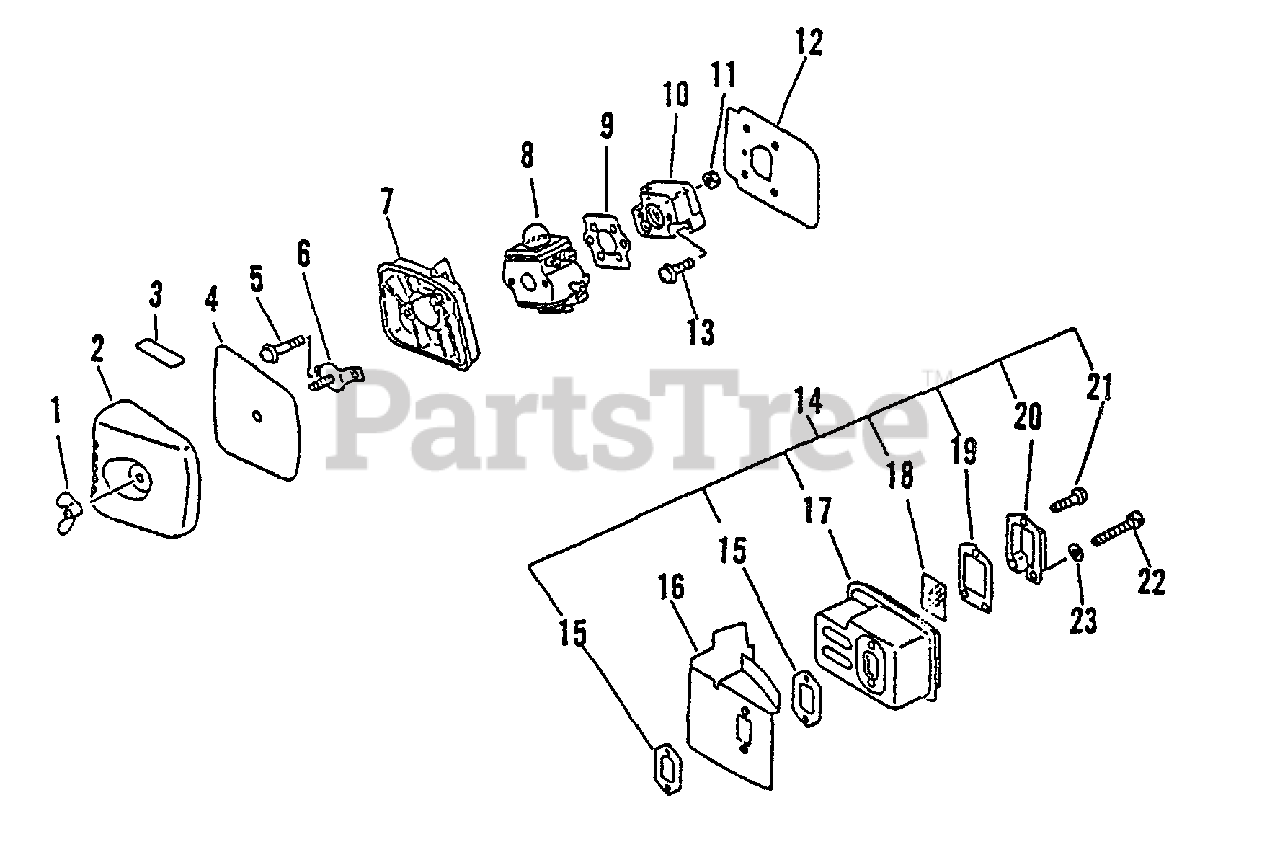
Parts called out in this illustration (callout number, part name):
1	WINGNUT - 6
2	COVER, AIR FILTER
3	LABEL - CHOKE
4	FILTER, AIR
5	SCREW - 5X64
6	PLATE, PREVENT
7	AIR FILTER CASE ASSY
8	CARBURETOR C1U-K17
9	GASKET, INTAKE
10	INSULATOR, INTAKE
12	SHIELD, INTAKE
13	SCREW - 5X20
14	MUFFLER ASSY
15	GASKET, EXHAUST
16	SHIELD, EXHAUST
18	SCREEN, SPARK ARRESTOR
19	GASKET, EXHAUST
20	GUIDE, EXHAUST - OUTER
21	SCREW - 4X10
22	SCREW - 5X50
23	WASHER - 5
